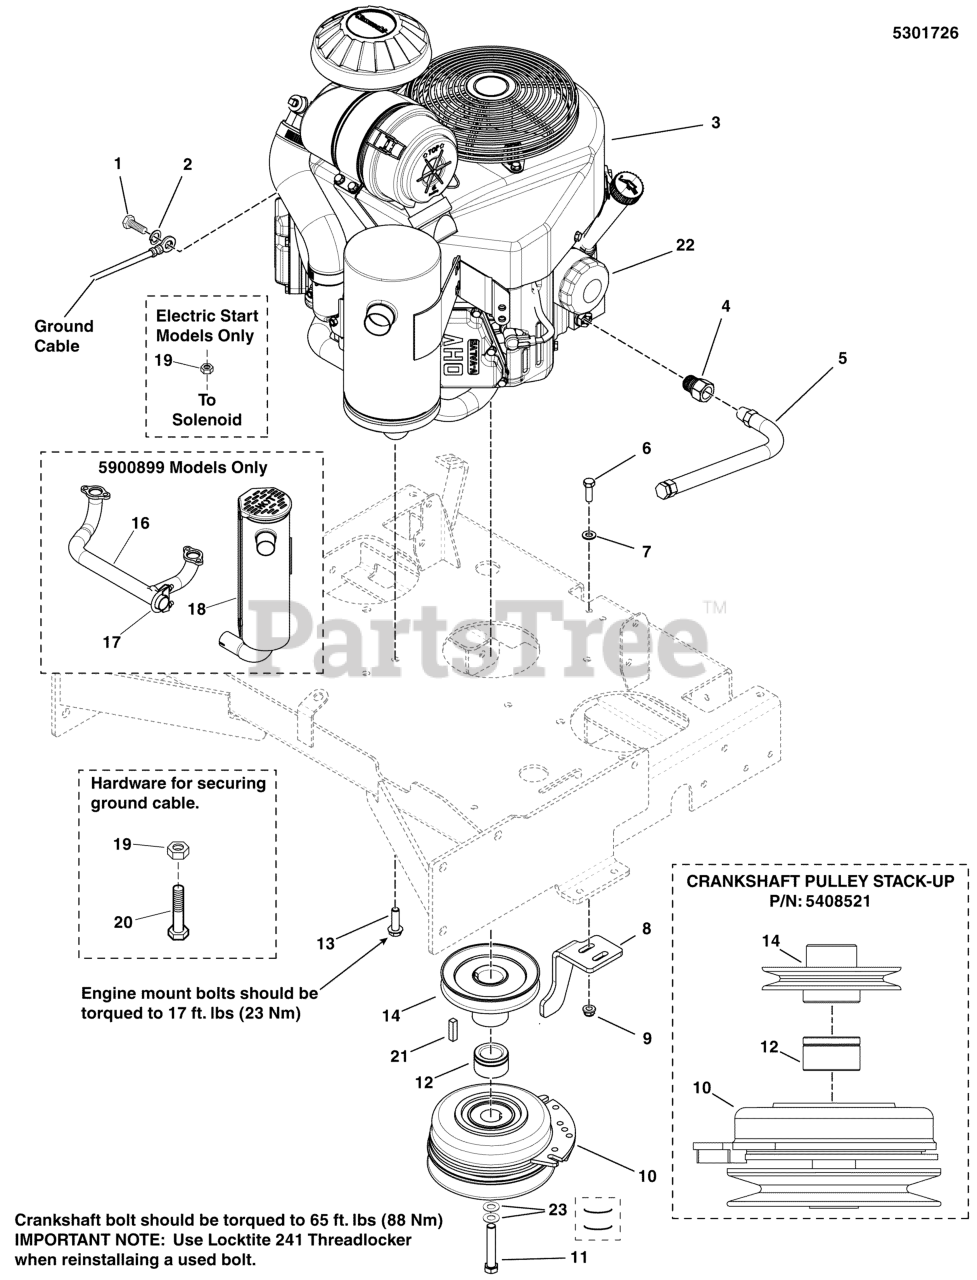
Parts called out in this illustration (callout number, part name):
1	BOLT, 5/16-18 X 3/4 GD5
2	WASHER, 5/16 LOCK CZ
3	ENGINE, KAWASAKI
4	ADAPTER-OIL DRAIN
5	HOSE, OIL DRAIN
6	BOLT, 5/16-18 X 1 GD5 YZ
7	WASHER, 5/16" SAE
8	PLATE, CLUTCH ANCHOR - RED
9	NUT, 5/16-18 HEX NYLOCK FLANGE
10	* CLUTCH, 5218-134, WARNER
11	BOLT, CRANKSHAFT,7/16-20X2-3/4, GD8
12	SPACER, 1.13 X 1.75 X 1.03
13	BOLT,HEX FLG,SER GD5 3/8-16X1-1/4PACH CZ
14	PULLEY, CRANKSHAFT, 1.125 ID X 4.50 OD
15	FILTER, AIR
16	MANIFOLD
17	CLAMP, MUFFLER & MANIFOLD
18	MUFFLER
19	NUT, M8-1.25 SERR. FLANGE, CZ
20	BOLT, M8-1.25 SERR. FLANGE, CZ
21	KEY, 1/4 SQ X 1
22	FILTER, OIL
23	BELLEVILLE WASHER 1.1875 X .442 X .089
